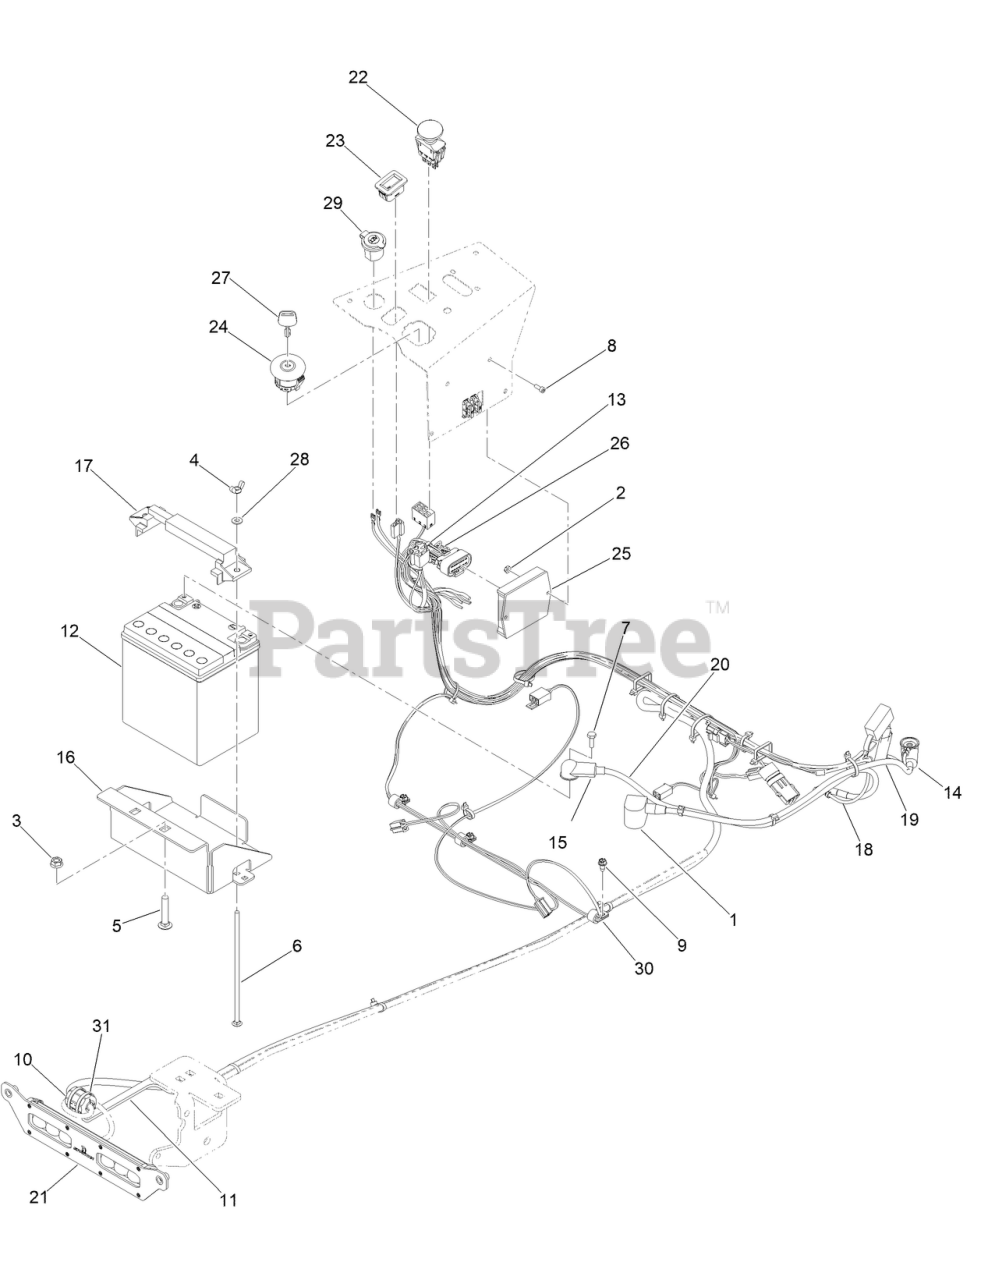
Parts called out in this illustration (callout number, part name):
1	INSULATOR-BATTERY
2	NUT-LOCK
3	3/8-16 HEX FLANGE NUT W/SERR ZINC YELLOW
4	NUT-WING
5	SCREW-CARR
6	1/4IN-20X8IN GR5 CARRIAGE BOLT
7	SCREW-HH
8	10-24 X 1/2 SOCKET C/S 18-8 SS
9	SCREW-HWH
10	FAIR-RITE ROUND CABLE SNAP-IT SIZE B
11	FAIR-RITE BRACKET PAINTED
12	BATTERY - ETX30LA - 400CCA
13	6IN (40 LB) CABLE TIE NYLON UV
14	3.15 LGTH STRAIGHT INSUL TERM COVER RED
15	STRAIGHT INSULATING TERMINAL COVER
16	MWR BATTERY BOX
17	BATTERY HOLD DOWN
18	VANGUARD 28/32/36 HP HARNESS
19	MWR POSITIVE BATTERY CABLE 25IN
20	MWR NEGATIVE CABLE 28
21	SPLIT BEAM W/NON-LIGHTD HELMET LIGHT BAR
22	PTO SWITCH
23	HOUR METER
24	IGNITION SWITCH
25	INTERLOCK MODULE
26	MWR KEYSWITCH JUMPER HARNESS
27	2023 MWR KEY
28	WASHER-FLAT
29	12 VOLT AUXILLIARY PLUG
30	CLAMP-R
31	TIE-CABLE
